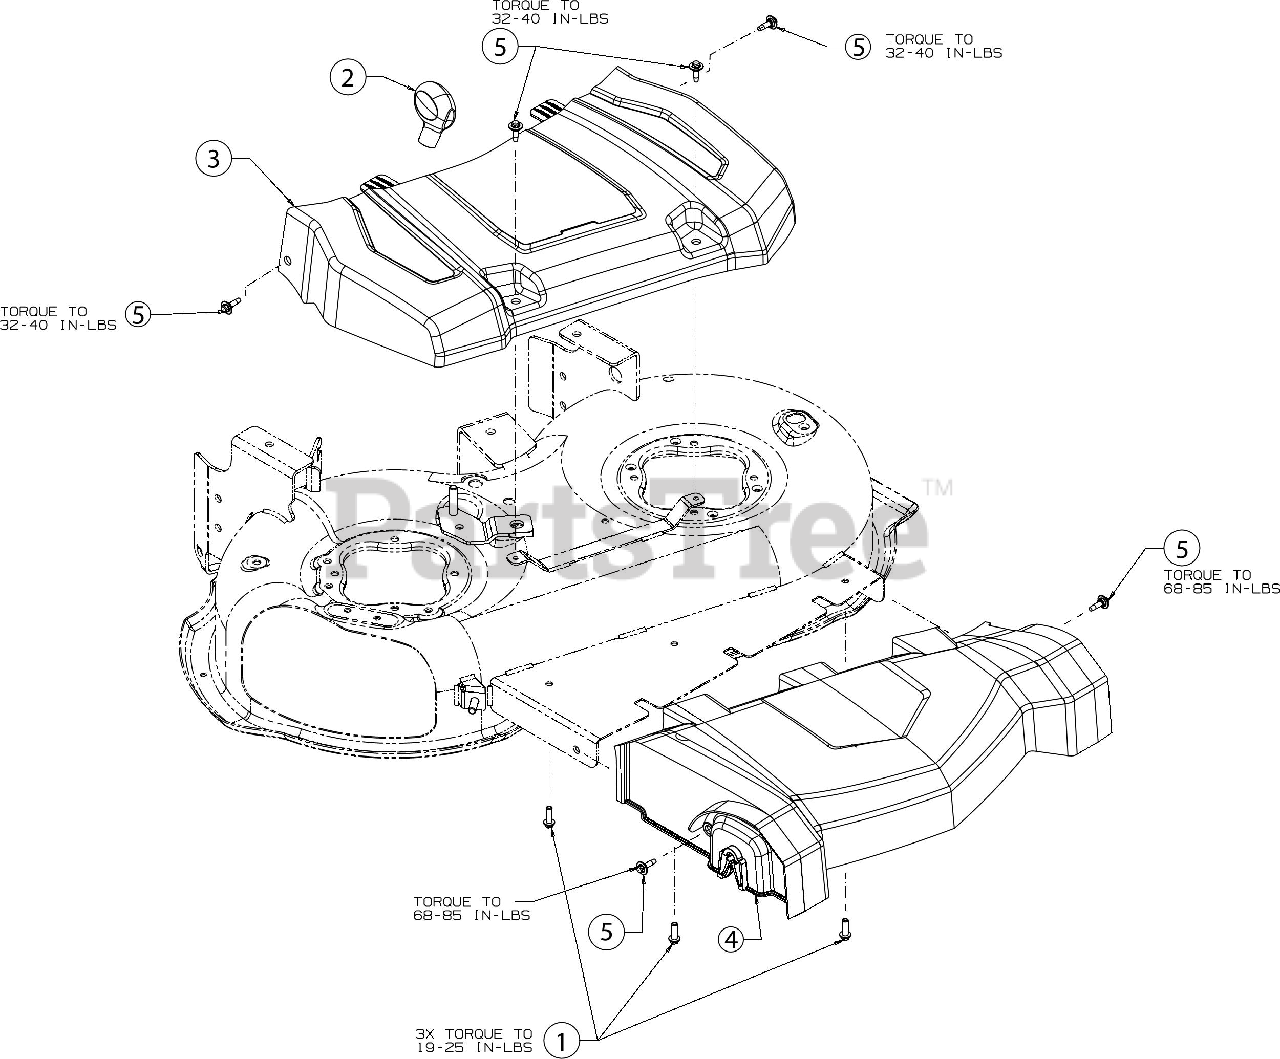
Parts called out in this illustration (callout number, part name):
1	SCREW 1/4 x .750
2	HEIGHT ADJUSTMENT KNOB
3	28" BELT COVER
4	FRONT AXLE COVER
5	SHOULDER SCREW M6-1 .368 X.115
